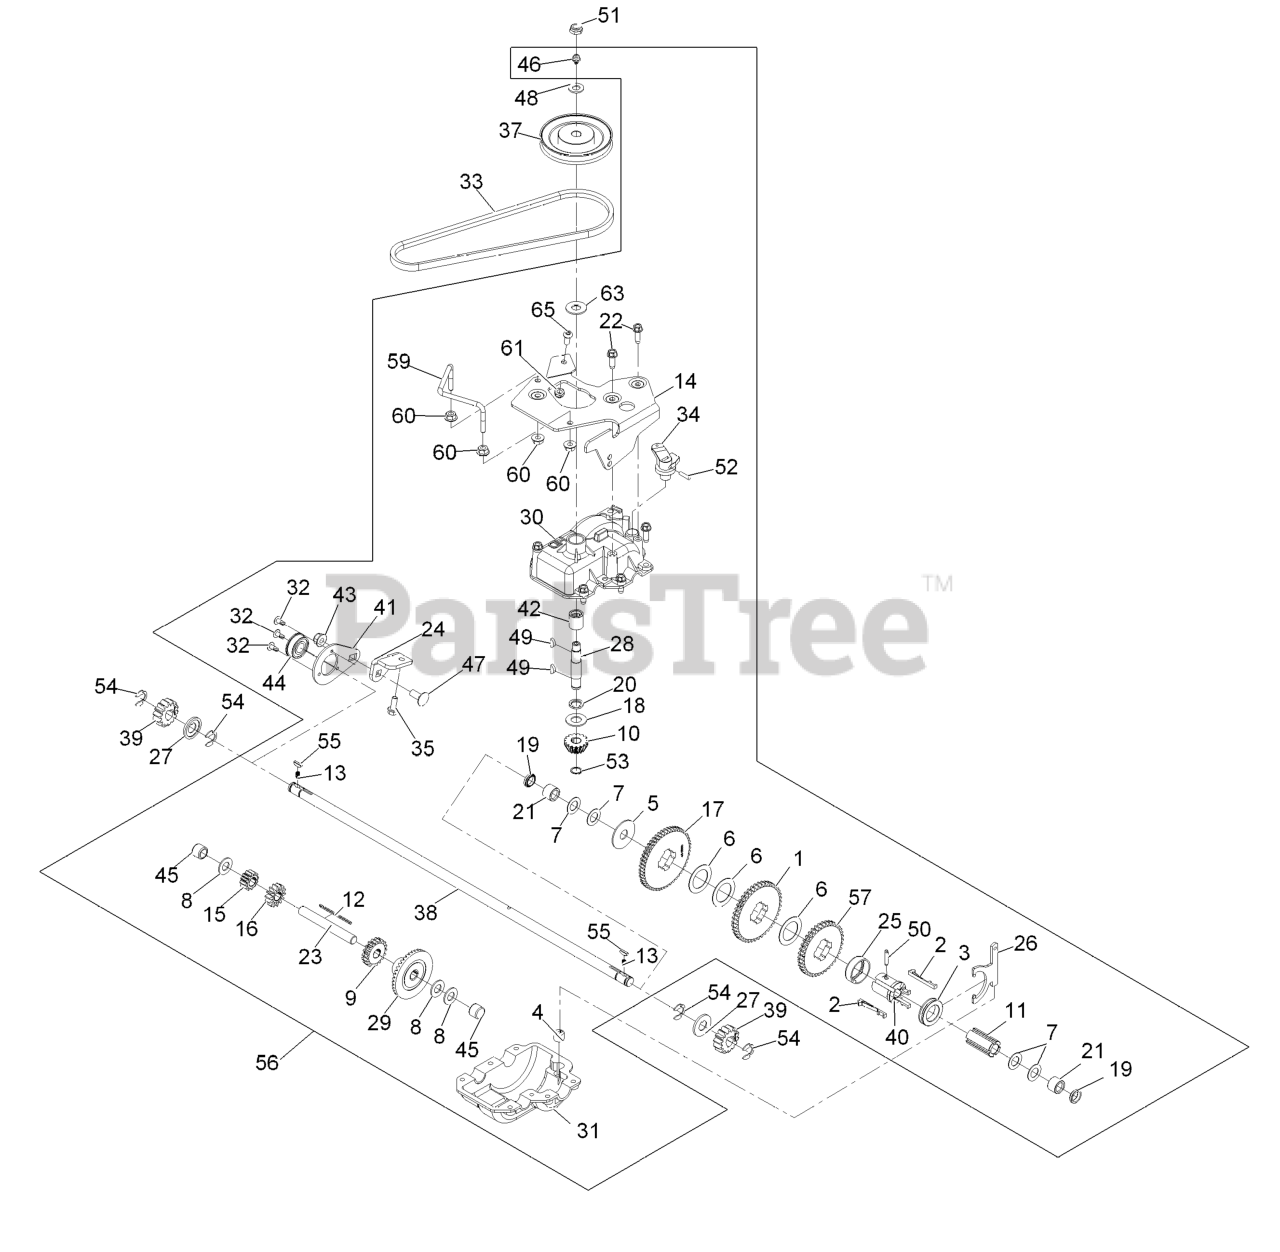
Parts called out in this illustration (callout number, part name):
1	GEAR-42T
2	KEY-SHIFT
3	COLLAR-SHIFT
4	BUSHING-YOKE
7	WASHER-PLAIN
8	WASHER-THRUST
9	GEAR-18T
10	PINION-BEVEL
13	SPRING-COMPRESSION
14	BRACKET-GUIDE, BELT
15	GEAR-12T
16	GEAR-14T
18	WASHER-THRUST
19	SEAL-OIL
21	BEARING-CAGED NEEDLE ROLL
22	SCREW-HWHTF
23	SHAFT-INTERMEDIATE
24	BRACKET-BEARING, PLATED
25	RETAINER-KEY
26	YOKE-SHIFT
27	WASHER-THRUST, OUTER
28	INPUT SHAFT ASM
29	GEAR-BEVEL
30	ASM,GEAR CASE W/BRG
31	GEARCASE-LOWER
32	SCREW-TAP
33	BELT-V, TRACTION
34	LEVER-SHIFT
35	SCREW-HWH
38	SHAFT-AXLE
39	GEAR-PINION
40	SLEEVE-4 DOG
41	PLATE-BEARING
42	BEARING-ROLLER, CAGED
43	NUT-HF, NI
45	BEARING-NEEDLE, CLOSED
46	FITTING-GREASE, ZERK
47	SCREW-CARR
48	WASHER-FLAT
49	KEY-WOODRUFF
50	PIN-GROOVE
51	NUT-HEX
52	PIN-SPRING
53	RING-RETAINING
54	RING-RETAINING
56	ASM,GEARBOX (SERVICE ONLY
57	GEAR-38T
59	GUIDE-BELT
61	NUT-LOCK, NI
65	SCREW-HSBH
